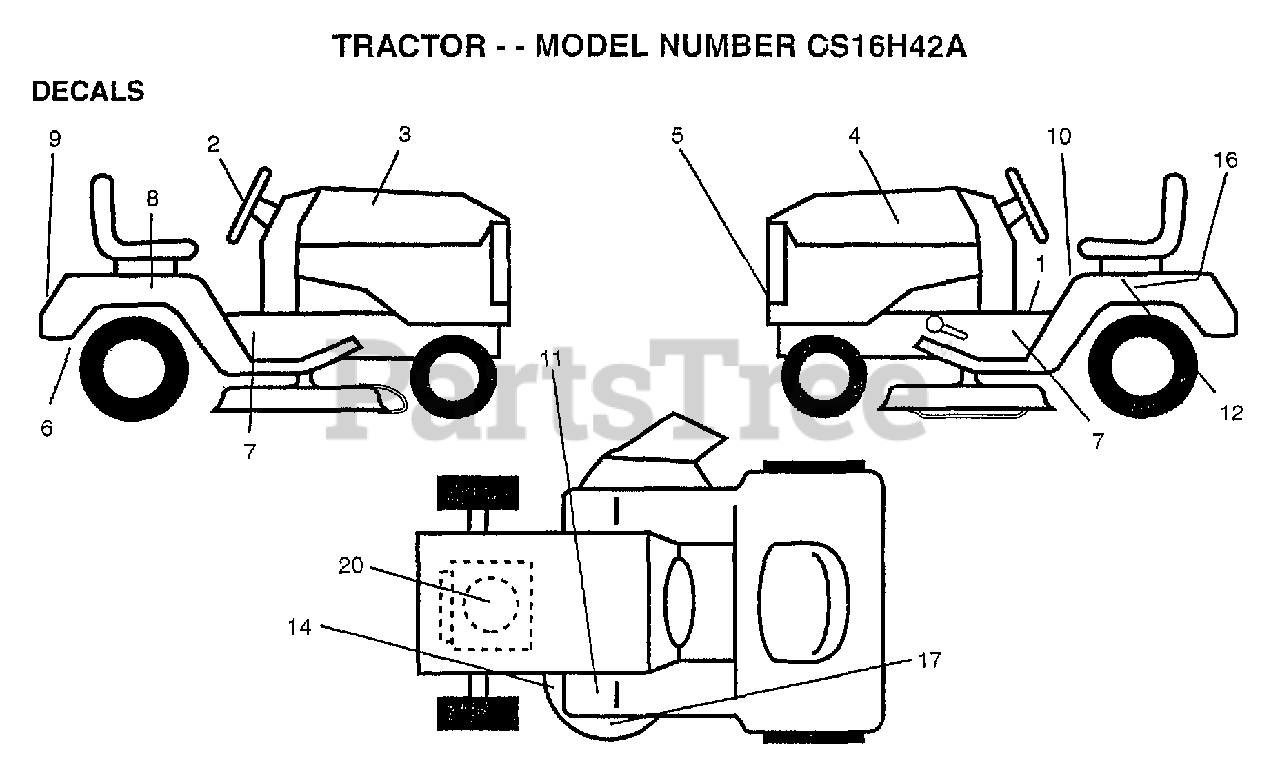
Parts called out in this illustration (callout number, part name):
1	"DECAL INST,SADDLE"
2	"DECAL INSERT,STRG"
3	"DECAL.HOOD,RH"
4	"DECAL.HOOD,LH"
5	DECAL.LENS.YP.EUR
6	DECAL DRAWBAR LH
7	DECAL CHASSIS
8	DECAL FENDER RH
9	DECAL FENDER
10	"DECAL DANGER,FEND"
12	DECAL FENDER LH
14	DECAL
16	DECAL.BATRY.3-3908
17	"DECAL,ENVIRO DECK"
20	DECAL, HP ENGINE
